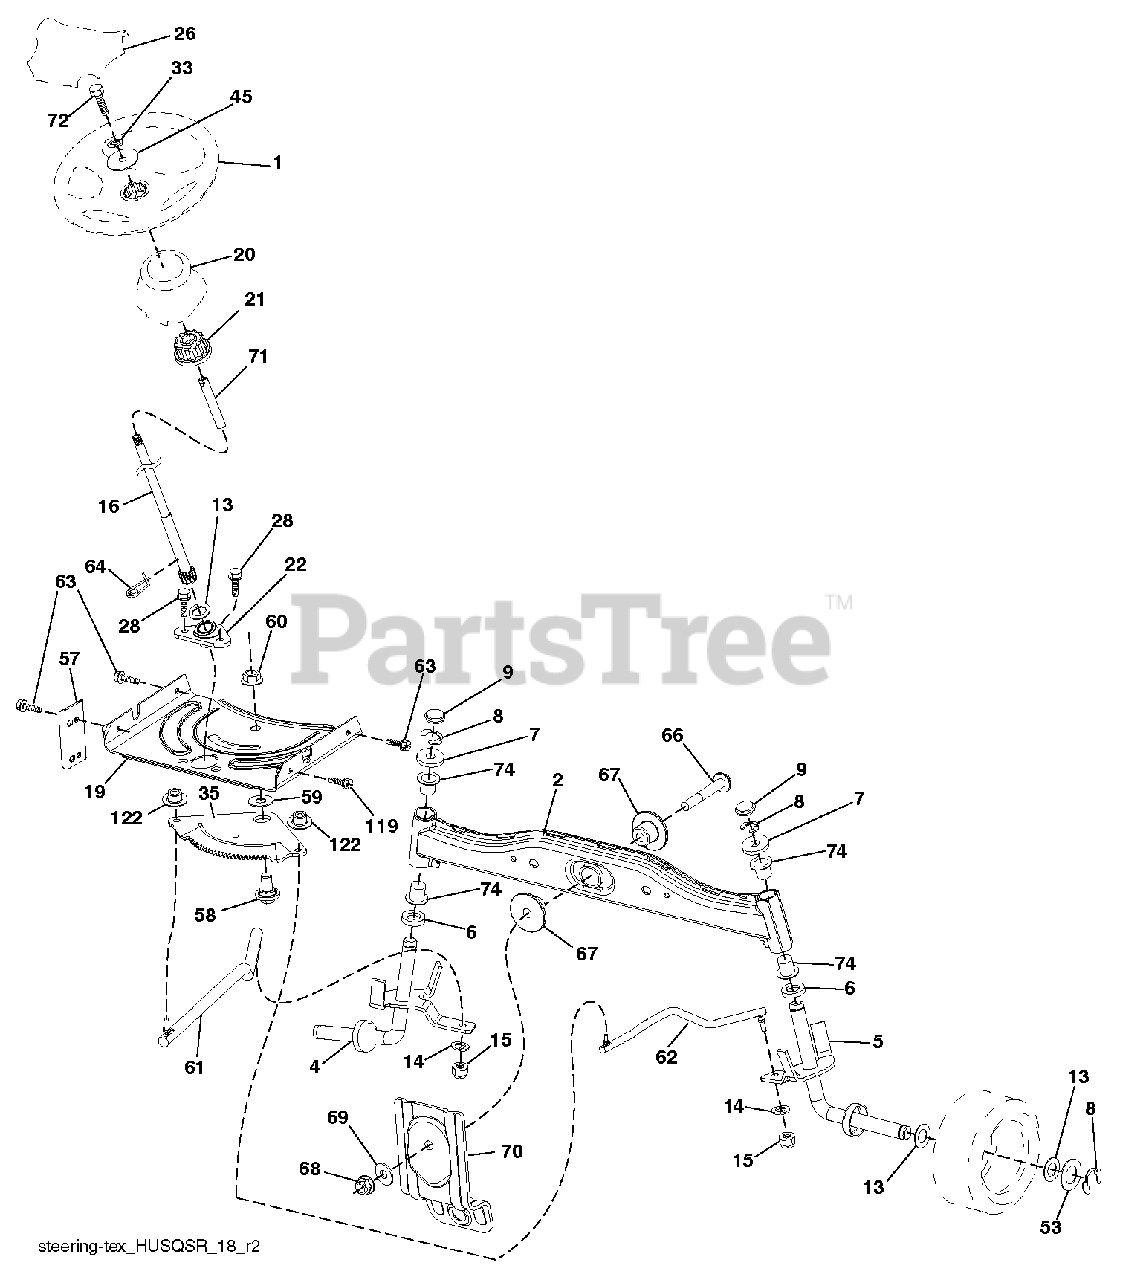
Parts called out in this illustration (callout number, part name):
1	WHEEL.STEER.HUSQ.SR.498.OVMLD
2	AXLE HALF ASM-WELDED
4	SPINDLE.STEERING.ASM.LH.13".TI
5	SPINDLE.STEERING.ASM.RH.13".TI
6	THRUST WASHER
9	CAP.SPINDLE.BLACK
14	WASHER, LOCK 3/8
15	NUT CROWNLOCK 3/8-24
16	SHAFT.STEER.3/4.PLATED.TEX
19	PLATE.STEER.DDL.NLT/NG
20	STEERING.BOOT.HUSQ.LT
21	ADAPTER, WHEEL STNG..
22	STEERING.SUPT.LOWER.
26	INSERT.CAP.WHL.STRG.HUSQ.PREM
28	SCREW, 3/8-16X3/4
33	LOCKWASHER
35	GEAR.SECTOR.PLATE.DDL.
45	WASHER.11/32
53	WASHER.HARDENED
57	BRACKET.UPSTOP.TEX
58	BOLT.SHOULDER.SECTOR.P
59	WASHER.THURST.SECTOR.S
60	NUT FLANGE LOCK 5/8-11
61	DRAGLINK.LH.BALLSTUD.D
62	DRAGLINK.RH.BALLSTUD.D
63	SCREW
64	RETAINER.CLIP.SPRING.S
66	BOLT HEX FGHD 7/16-14 X 3 SERR
67	BUSHING.PM.FRONT AXLE
68	NUT.LOCK.FLANGE.7/16
69	WASHER.1.5X.505X.118
70	BRACKET.SUSP.MWR.FRT.30"SRD
71	SHAFT.EXTEN.STRG.SPLINE
72	BOLT 5/16-18 X 4 W/PATCH
74	BRNG T
119	SHOULDER BOLT 5/16-18TT
122	CAP.GEAR.SECTOR.TEX
